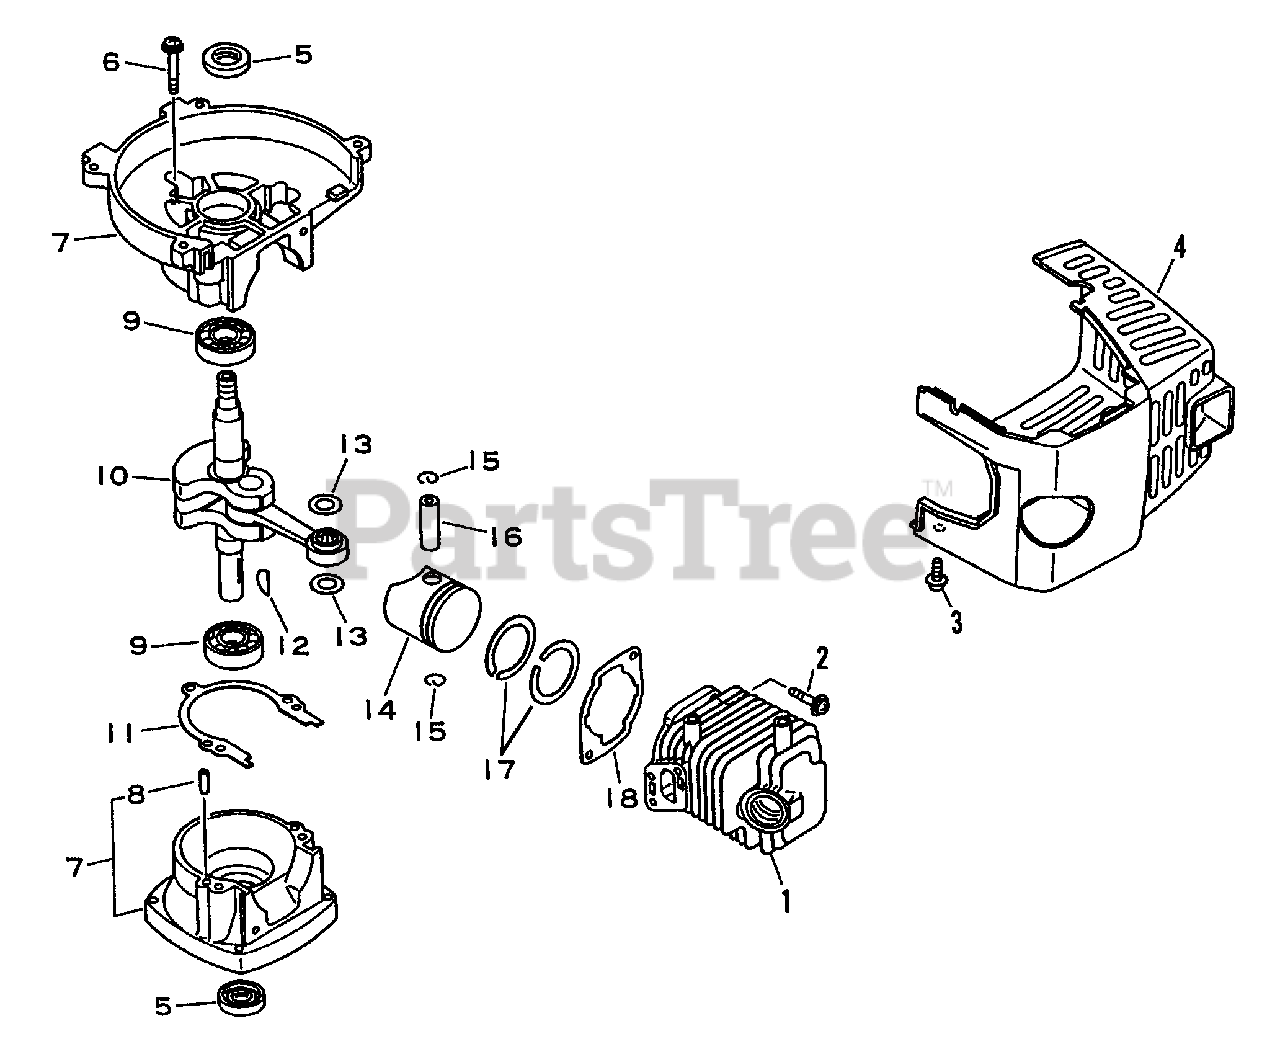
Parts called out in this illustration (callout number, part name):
1	CYLINDER
2	SCREW 5×22
3	SCREW 4×18
4	COVER, ENGINE
5	SEAL, OIL 12
6	SCREW 5×28
7	CRANKCASE KIT
8	PIN, LOCATING 4
9	BEARING, BALL - 6201 C3
10	CRANKSHAFT ASSY
11	GASKET, CRANKCASE
13	WASHER, THRUST
14	PISTON
15	RING, SNAP
16	PIN, PISTON 8
17	RING, PISTON
18	GASKET, CYLINDER
19	BEARING, NEEDLE
